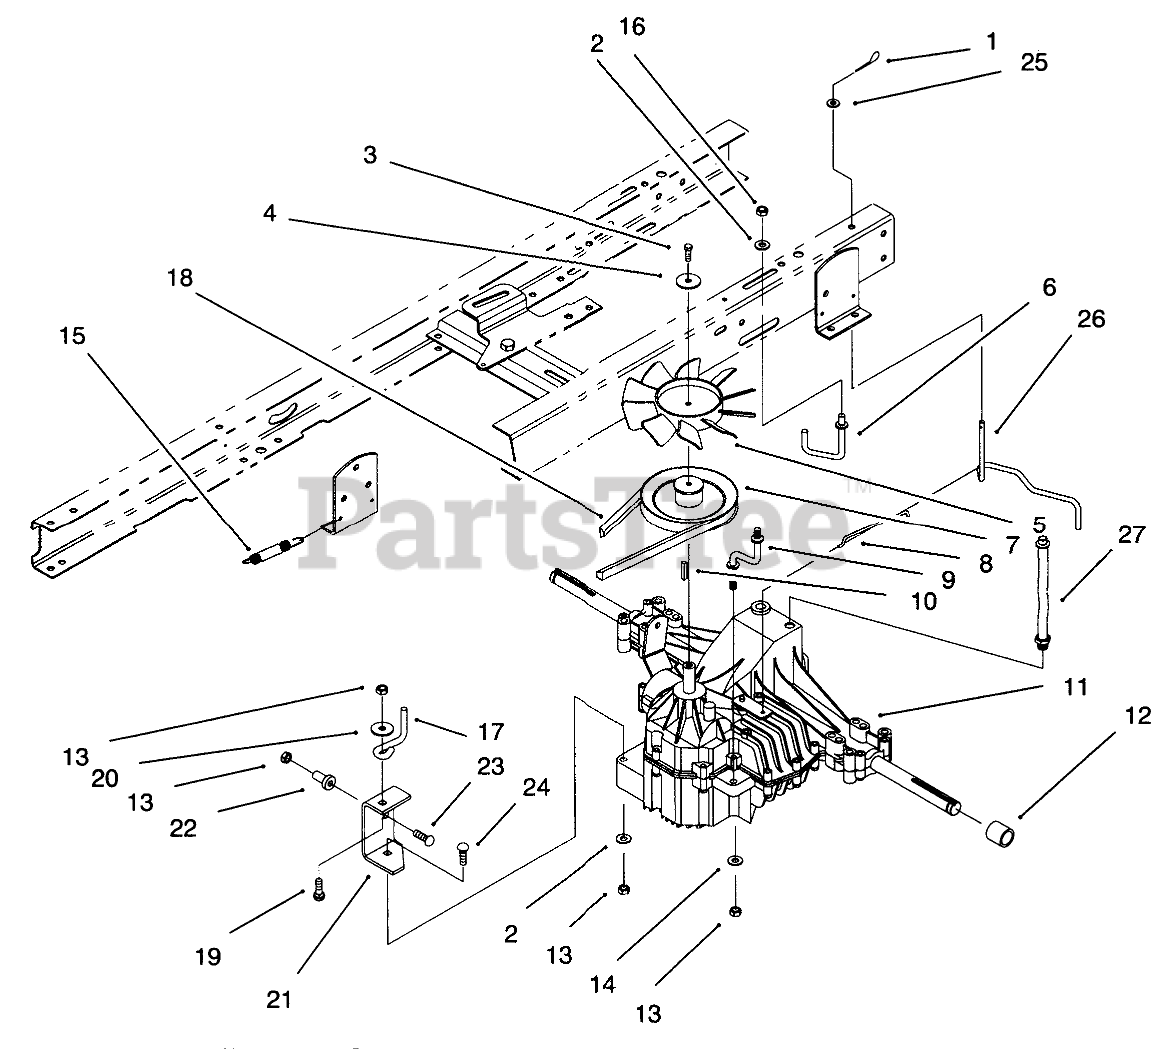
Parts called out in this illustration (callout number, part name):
1	PIN-COTTER
2	WASHER-PLAIN
3	SCREW-HH
4	WASHER-FLAT
5	FAN-7"
6	GUIDE-TRANS BELT, LH
7	HYDRO TRANS PULLEY
8	WIRE - BYPASS
9	TORQUE STRAP
10	KEY-PUMP
11	TRANSAXLE ASM-HYDRO
12	SPACER
13	NUT-LOCK, NI
14	WASHER-PLAIN
15	SPRING-RETURN, BRAKE
16	NUT-KEPS
17	TRANS BELT GUIDE
18	V-BELT
19	BOLT-CARR
20	WASHER-PIVOT
21	Bracket-Speed Control
22	BUSHING-FLANGE
23	SCREW-CARR
24	BOLT-CARR
25	WASHER-FLAT
26	LEVER - BYPASS
27	ASM - BREATHER HOSE
